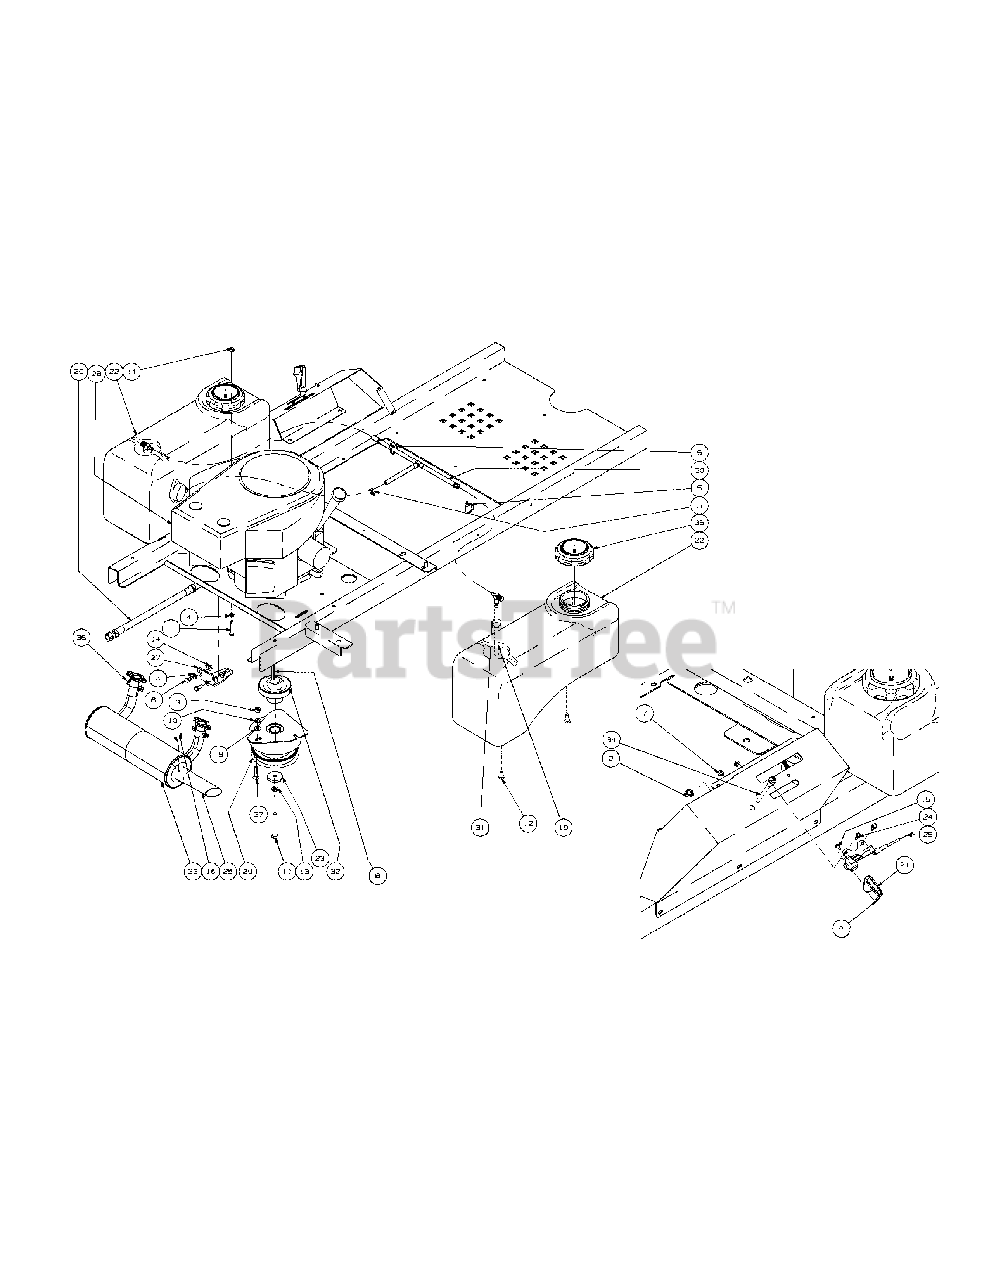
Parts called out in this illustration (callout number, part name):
1	HHCS, 5/16-18, 1-1/2
2	Jam Nut, 3/8-24
3	Hex Nut, 5/16-18
4	Flat Washer, 5/16
5	Cable Tie, 3/16 x .05 x 7.4
6	Hex Cap Screw, 5/16-18 x .75
7	Lock Nut, Nylon Insert, 10-32
8	Key, .25 x .25 x 2.00
9	Nut, w/ Star Washer
10	Lock Washer, 5/16
11	Hose Clamp, SAE #4: 1/4-5/8, SS
12	Hex Cap Screw, 3/8-16 x .500
13	Lock Washer, 7/16
14	Lock Nut, Hex Flange, 5/16-18
15	Machine Screw, 8-32 x .375
16	Screw, 8-32 x .375, Hex Washer
17	Hex Cap Screw, 7/16-20 x 3.00
18	Washer, 3/8 x .738 x .063
19	Fuel Pickup Fitting
20	Oil Drain Extension Hose
21	Throttle Control Knob
22	Fuel Tank
23	Flat Washer, 7/16 ID x 1.75 OD x .250
24	Screw, #10-32 x 0.500
25	Exhaust Pipe
26	Throttle Control Cable
27	Clutch Retainer Assembly
28	23HP Kawasaki Engine
29	Electric Clutch
30	Fuel Hose Assembly includes:
30	Hose, 1/4" Fuel Line
31	Fuel Tank Groment
32	Transmission Drive Pulley
33	Kawasaki Muffler
34	Choke Cable
36	Nut, M8-1.25, Hex Flange
37	Carriage Bolt, 5/16-18 x 1.75
